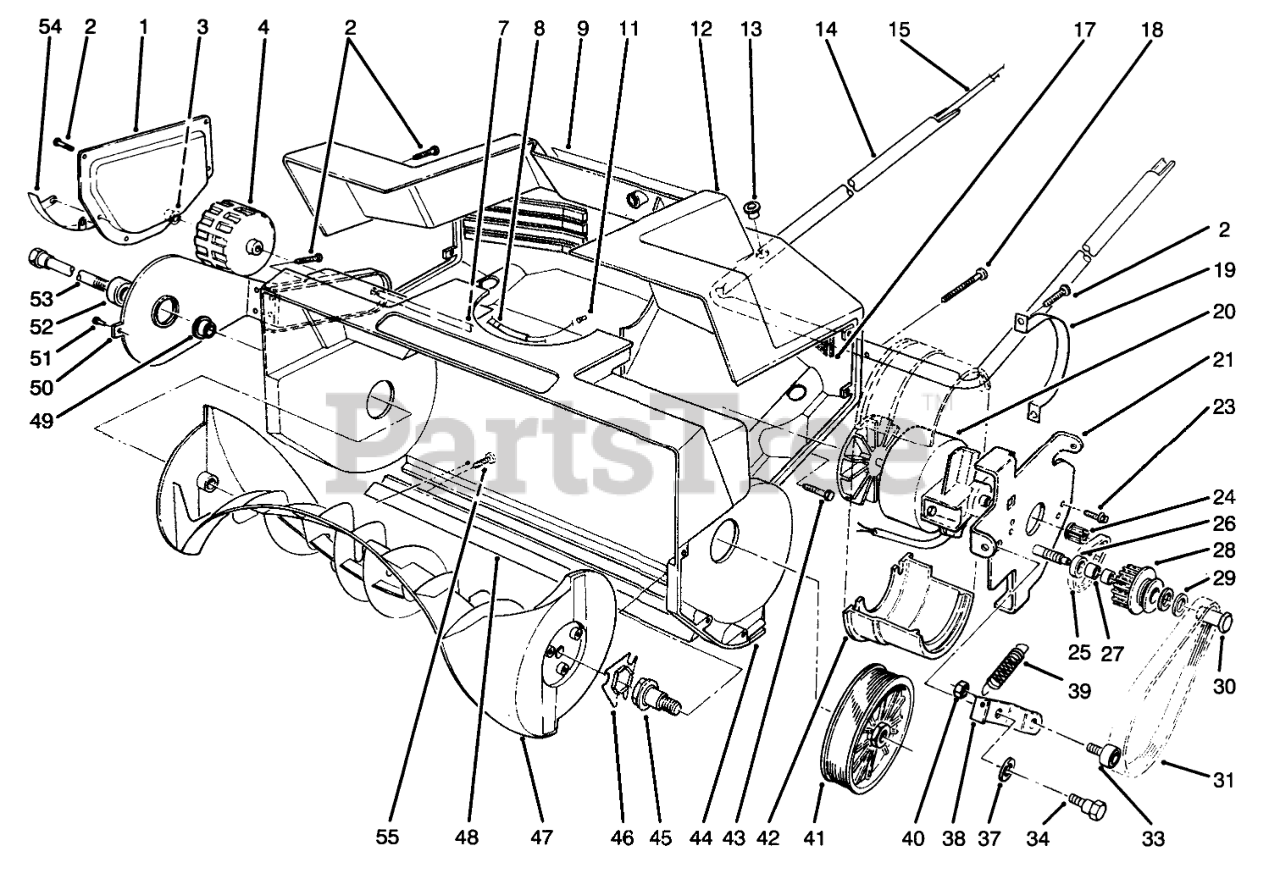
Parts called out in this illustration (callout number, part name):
1	Plate-Side
2	Screw
3	PUSHNUT-CAP, WASHER
4	Wheel
7	Shaft-Axle
8	Relief-Strain
9	Decal-Danger
11	Connector
12	Shroud-Housing
13	BUSHING
14	Tube-Lower Handle
15	Wire Harness
17	Filter-Foam
18	Screw-Pan Head
19	Strap-Motor
20	Motor
21	Motor Plate ASM
23	Screw-Hex Washer Hd.
24	Pulley-Driver
25	BELT-PULLEY, IDLER/DRIVER
26	WASHER
27	Bearing-Needle
28	Pulley Assembly-Idler (Incl. Ref. #27)
29	WASHER-THRUST
30	Bolt-Idler
31	Belt-Drive
33	Bearing Assembly (Incl. Ref. #40)
34	SCREW-SHOULDER
37	WASHER
38	Bracket-Idler
39	Spring
40	NUT-LOCK, NI
41	Pulley-Driven
42	Clamp-Motor Bracket
43	SCREW-HH
44	Housing-Rotor
45	Shaft-Driver, Rotor
46	Coupler-Rotor
47	Rotor
48	Scraper
49	BUSHING
50	Bracket-Wheel (Incl. Ref. #52)
51	RIVET-POP
52	Bearing-Ball
53	Shaft-Rotor
54	Skid-Housing
55	Screw-Pan Head
